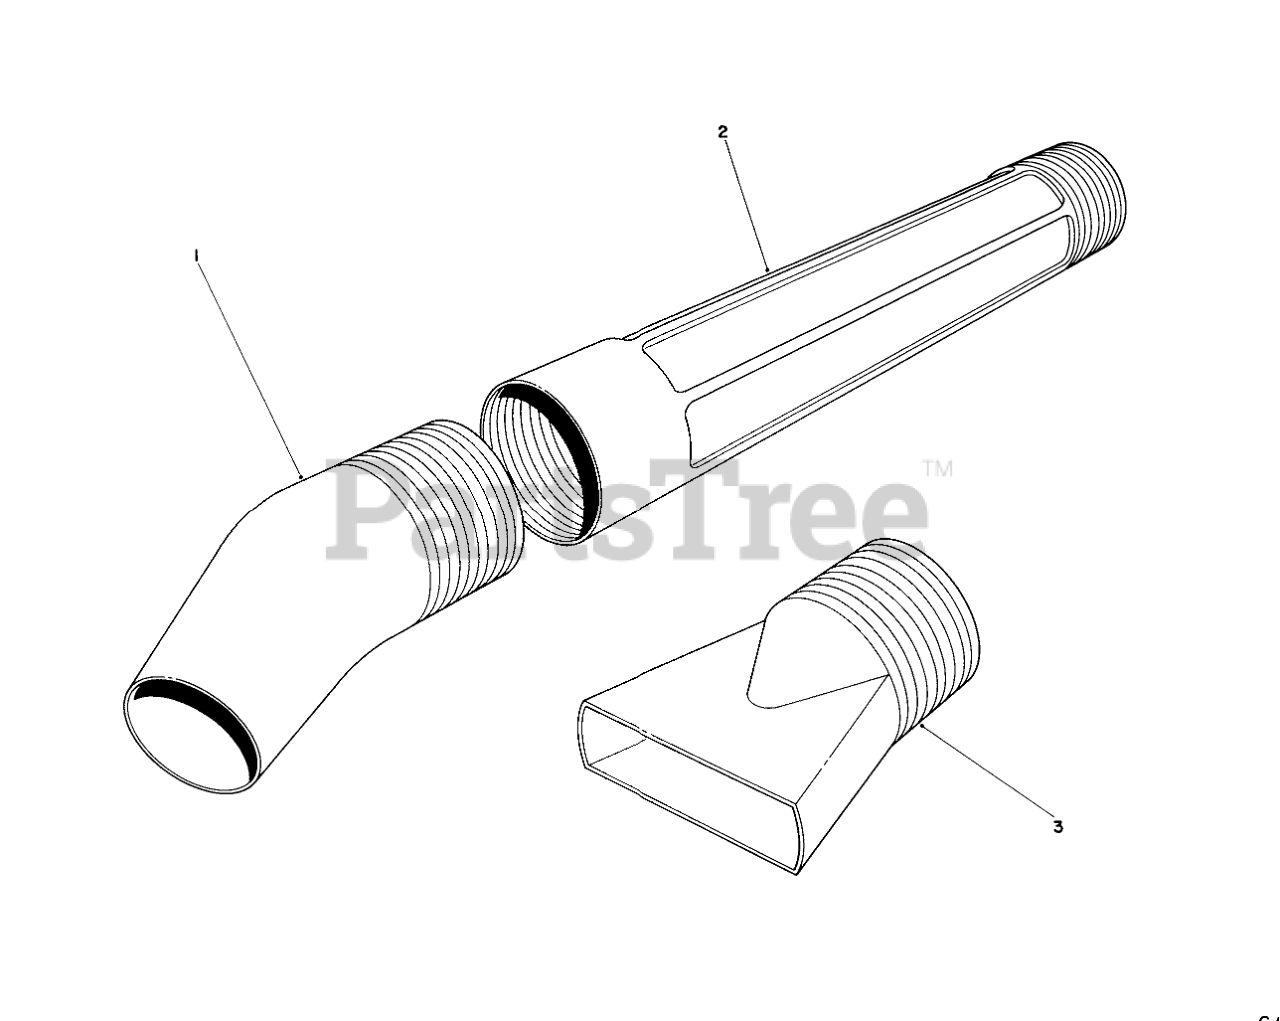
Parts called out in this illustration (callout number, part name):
1	NOZZLE--CONCENTRATING
2	BLOWER TUBE
3	Nozzle-Diffusing (Model No. 51545)
